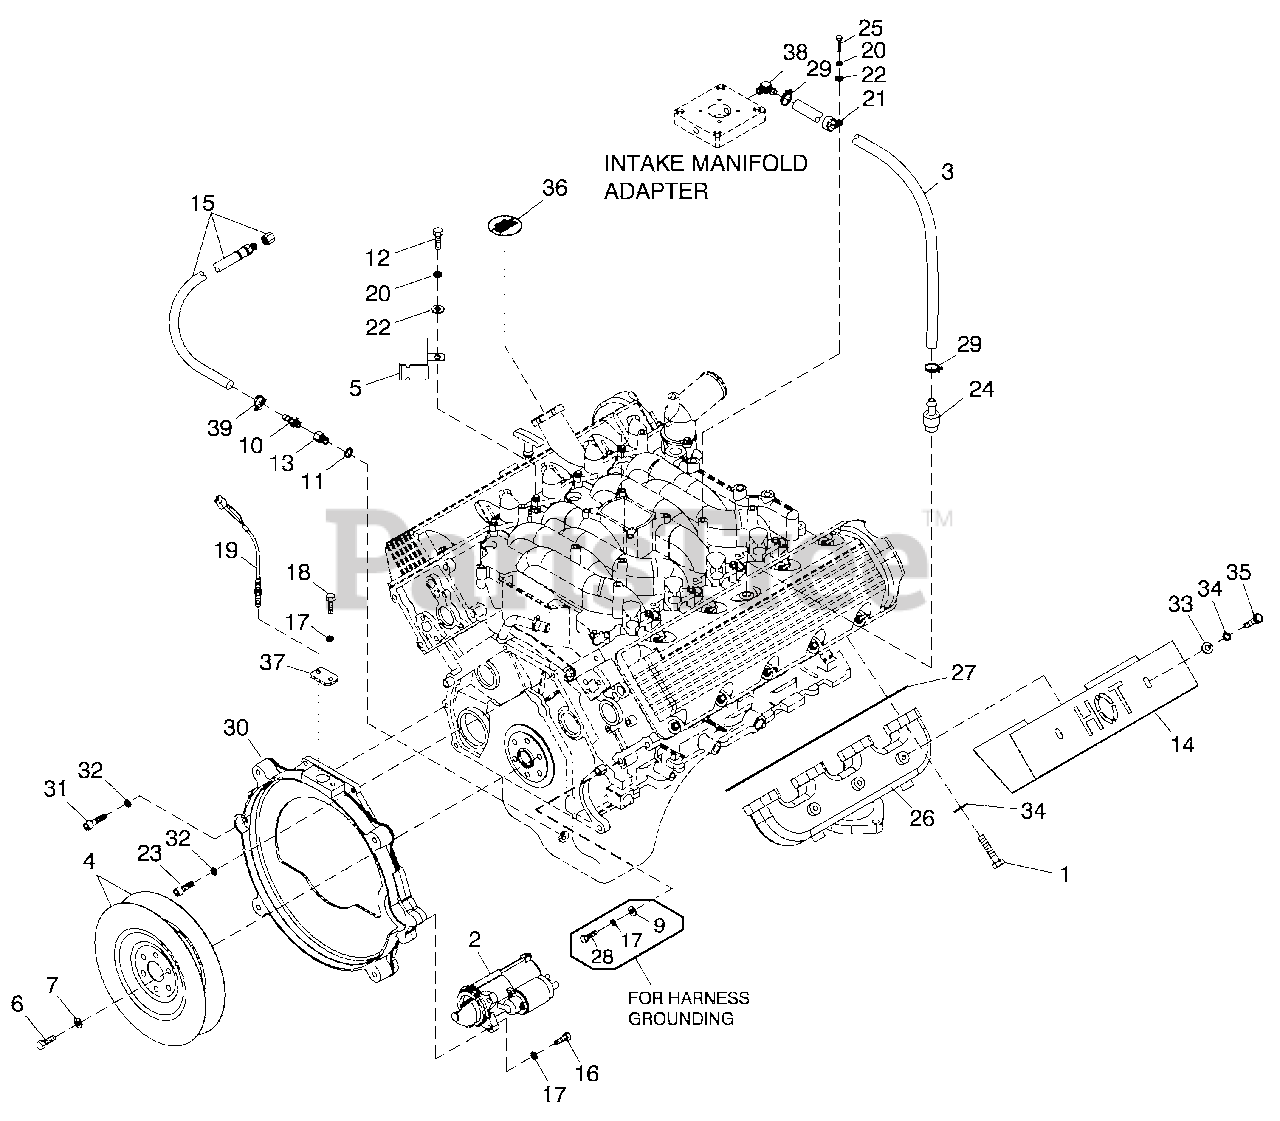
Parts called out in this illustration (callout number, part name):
1	SCREW SHC M8-1.25 X 35 SS
2	STARTER MOTOR 12V
3	HOSE 3/8 ID SINGLE BRAID (12"LG)
4	FLEX PLATE 2 POLE 4.6L G3
5	BRACKET, SIGNAL CONDITIONER
6	SCREW HHC M10-1.0 X 25 G10.9
7	WASHER FLAT .43 X 1.00
9	WASHER FLAT 5/16-M8 ZINC
10	BARBED STR 3/8 NPT X 3/8
11	WASHER NYLON .565
12	SCREW HHC M6-1.0 X 20 G8.8
13	ADAPTER M14-1.50 X 3/8 NPT
14	HEAT SHLD EXHAUST MANIFOLD
15	HOSE DRAIN ASSY 28"
16	SCREW HHC M8-1.25 X 30 G8.8
17	WASHER LOCK M8-5/16
18	SCREW HHC M8-1.25 X 20 G8.8
19	ASSY MAGPICKUP(3/8-24 MALE)
20	WASHER LOCK M6-1/4
21	CLAMP VINYL .75 X .343 Z
22	WASHER FLAT 1/4 ZINC
23	SCREW SHC M10-1.5 X 30 G12.9
24	VALVE PCV G3
25	SCREW HHC M6-1.0 X 16 G8.8
26	MACHINED MANIFOLD,EXHAUST
27	GASKET, EXHAUST MANIFOLD
28	SCREW HHC M8-1.25 X 25 G8.8
29	HOSE CLAMP BAND 5/8"
30	ENGINE ADAPTER
31	SCREW SHC M10-1.5 X 55 G12.9
32	WASHER LOCK M10
33	WASHER FLAT M8 SS
34	WASHER LOCK M8 SSTL
35	SCREW HHC 5/16-18 X 1/2 SSTL
36	DECAL REFER TO OWNERS MANUAL
37	PLATE MAG PICK-UP ADAPTOR
38	BARBED EL 90 1/4NPT X 3/8
39	CLAMP HOSE .38-.87
